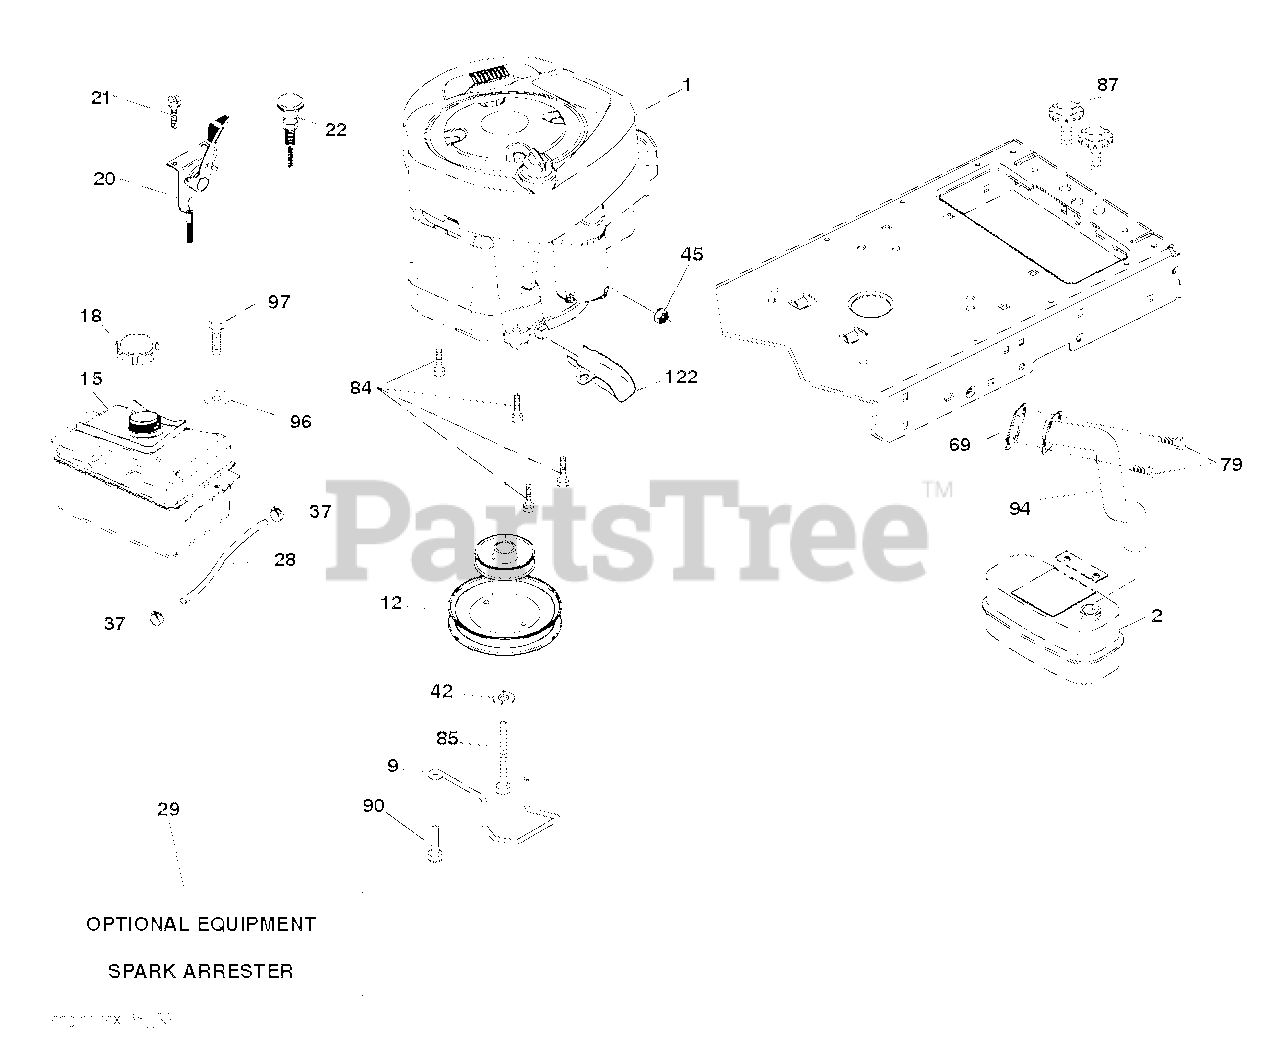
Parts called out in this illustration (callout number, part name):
2	MUFFLER.SINGLE.CYL.KOHL/B&S
9	KEEPER.BELT.ENGINE.3.25
12	PULLEY ENGINE
15	TANK FUEL FRT 1.5 GAL
18	CAP ASM.FUEL.2.25"FR.
20	CONTROL.TH/CK.C.
21	SCREW.#10 X 0.750.BOS THREAD
28	LINE.FUEL.20
29	ARRESTER SPARK (OPTIONAL)
37	HOSE CLAMP
42	LOCKWASHER
45	NUT
69	REPL BY 532 27 22-93
79	SCREW.SOCKET HD.5/16-1
84	SCREW.3/8-16
85	BOLT HEX 7/16-20X4-1/4"
87	BOLT, 5/16-18 X 1 3/4
90	SCREW 3/8-16X1
94	Exhaust Tube, B&S 28/31
97	SCREW HEXWSHR 1/4-20X3/4
122	EXTENSION DRAIN OIL
